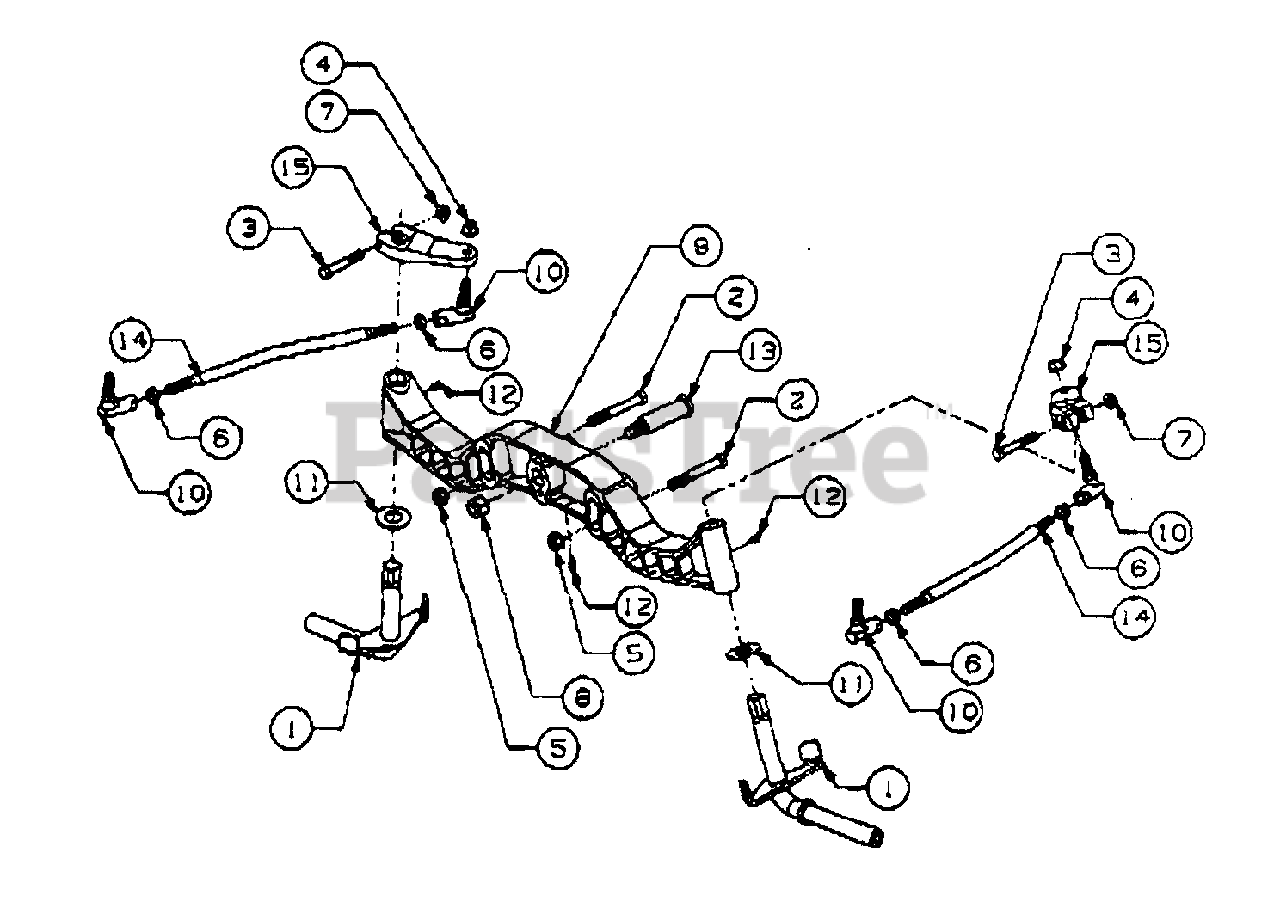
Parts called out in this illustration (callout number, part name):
1	Knuckle Assembly, Steering
2	Screw, Hex Cap, 3/8-16 x 2.75 Lg GR8
3	Screw, Hex Cap, 5/16-18 x 2.0 Lg GR5
4	Nut, Hex Lock, 3/8-24 GR5
5	Nut, Hex Flanged Lock, 3/8-16
6	Nut, Hex Jam, 3/8-24 GR5
7	Nut, Hex Range Top Lock, 5/16-18
8	Nut, Hex Top Nylon Lock, 1/2-13
9	Axle, Front Pivot
10	Joint, Ball, 3/8-24
11	Washer, Flat, .760 x 1.49 x .06 Thk.
12	Fitting, Lube, 3/16 Drive Type
13	Bolt, Pivot Shoulder, 3/4 Dia x 2.23
15	Arm, Steering
